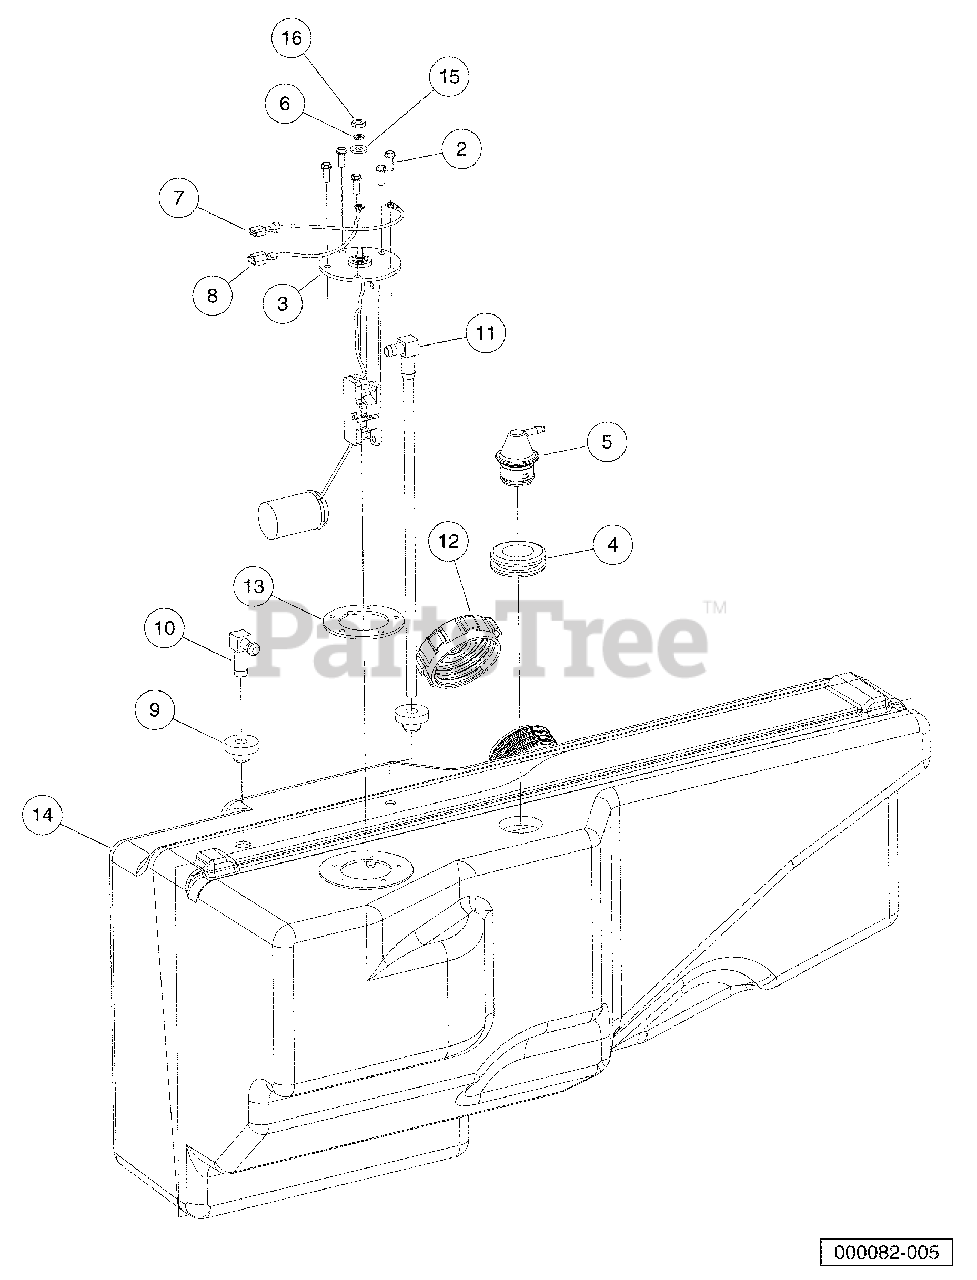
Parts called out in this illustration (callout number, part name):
1	Asm, Tank, Fuel, Diesel, 4x4
2	Screw, #10-16 Hex-Head Hi-Lo
3	Sending Unit, Fuel Level *
4	Insulation Grommet
5	Vent, Fuel Tank
6	Washer, #10 Split Lock
9	Bushing, Line, Return
10	Elbow, 90 Barbed
11	Pickup Tube, Fuel
12	Cap, Fuel (Diesel)
13	Gasket, Rubber
15	Washer, #10 Type A Flat
16	Nut, #10-32 Brass Hex.
